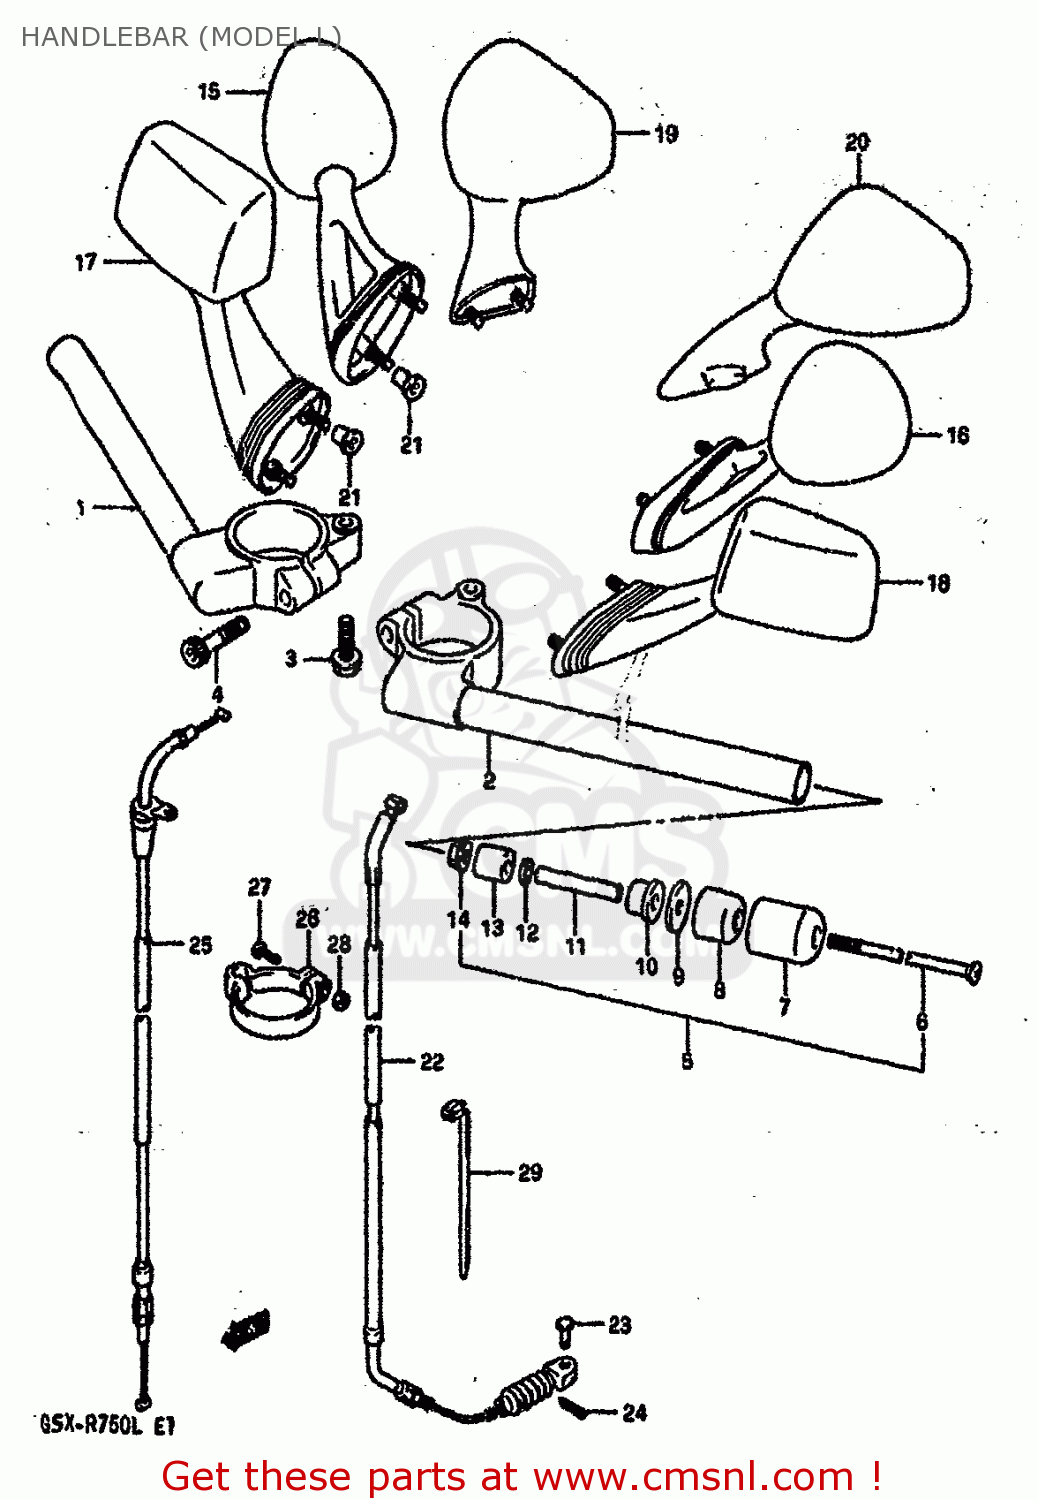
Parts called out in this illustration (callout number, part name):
1	HANDLEBAR,R
2	HANDLEBAR,L
3	BOLT
4	BOLT 8X35
5	BALANCER SET,HANDLEBAR
6	SCREW(6X127)
7	CAP,BALANCER
8	BALANCER,HANDLEBAR
9	SPACER,BALANCER
10	EXPANDER,HANDLE BALANCER
11	SPACER,EXPANDER
12	WASHER
13	EXPANDER,HANDLE BALANCER
14	NUT
15	MIRROR ASSEMBLY,REAR VIEW
16	MIRROR ASSEMBLY,REAR VIEW
17	MIRROR ASSY,REAR VIEW RH (BLACK)
18	MIRROR ASSY,REAR VIEW LH (BLACK)
19	CLAMP(L:235)
20	MIRROR ASSY,REAR VIEW LH (WHITE)
21	NUT,RR VIEW MIRROR
22	CABLE ASSEMBLY,CLUTCH
23	PIN(L:15)
24	PIN
25	CABLE ASSEMBLY,THROTTLE
26	CLAMP,CLUTCH CABLE
27	SCREW
28	NUT ,5MM
